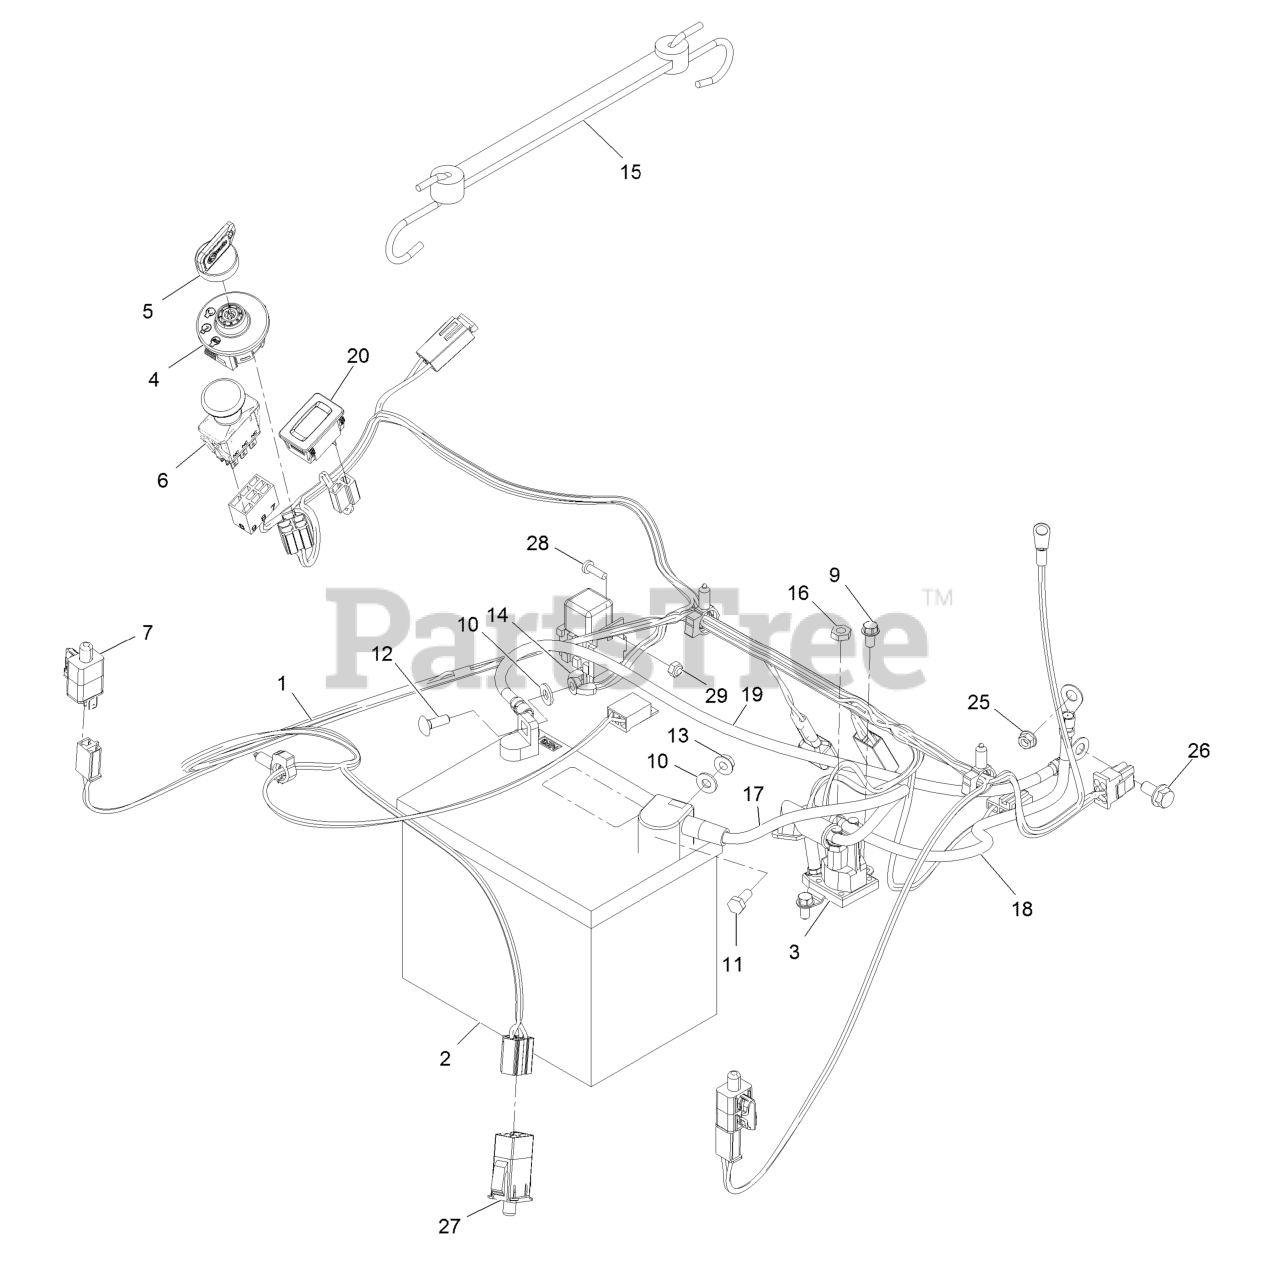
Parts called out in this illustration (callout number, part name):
1	Harness-Wire
2	Battery
3	Solenoid
4	Switch-Ignition
5	Key-Exmark Logo
6	Switch-PTO
9	Screw-HWH 1/4-20 X 1/2 Taptite
10	Washer-1/4 SAE
11	Screw-HH 1/4-20 X 5/8
12	Bolt-Carriage 1/4-20 X 3/4
13	Nut-Whizlock 1/4-20
14	Nut-Wing
15	Holddown-Battery
16	Nut-Jam 5/16-24
17	Cable-Battery, Red
18	Cable-Battery, Positive
19	Cable-Battery, Black
20	Hourmeter
25	Nut-Hex M6-1 Flg
26	Screw-HH Flg 5/16-18 X 5/8
27	Switch-Delta
28	Screw-PPH #10-24 X 5/8
29	Nut-Nyloc #10-24
